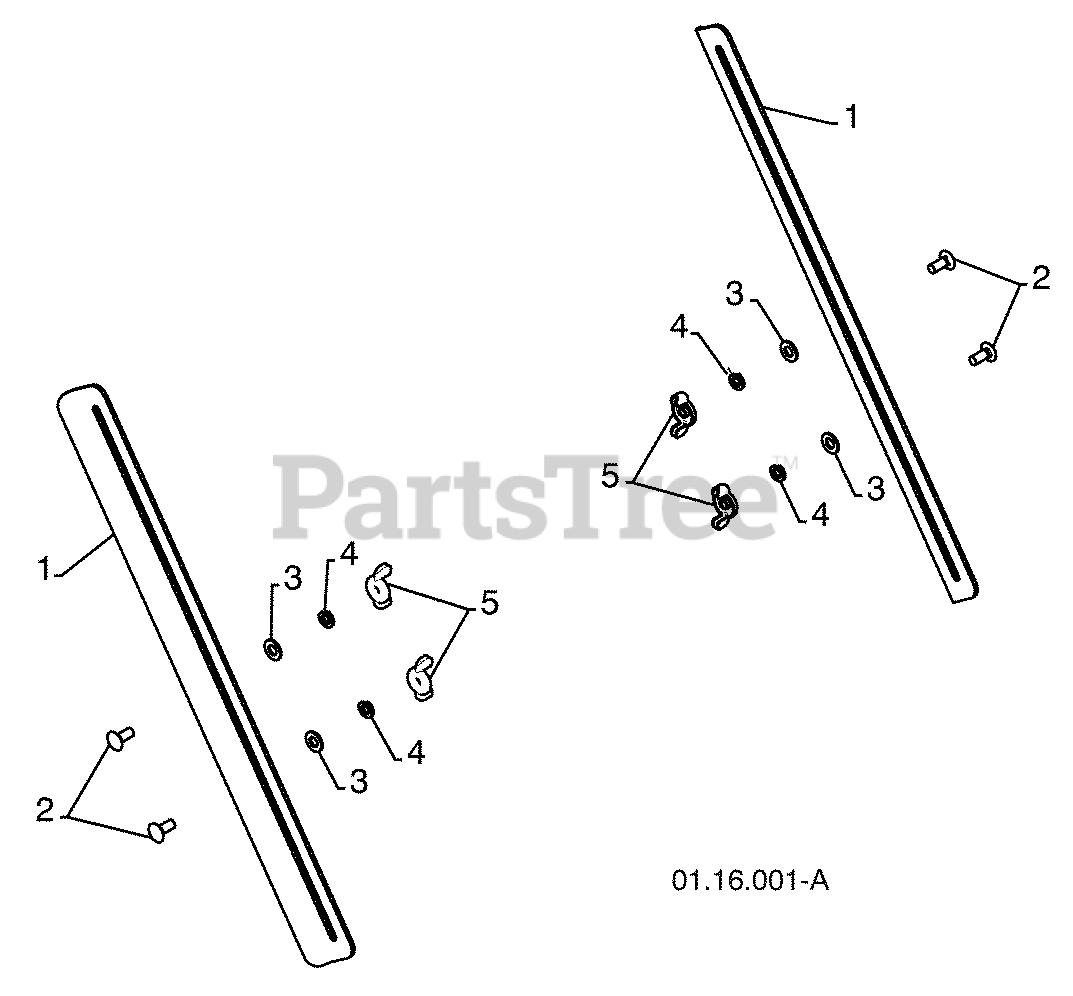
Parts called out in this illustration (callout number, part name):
1	DRIFT CUTTER BAR
2	CARRIAGE BOLT 5/16-18 X .750
3	PLASTIC WASHER
4	LOCKWASHER 5/16
5	NUT 5/16-18
